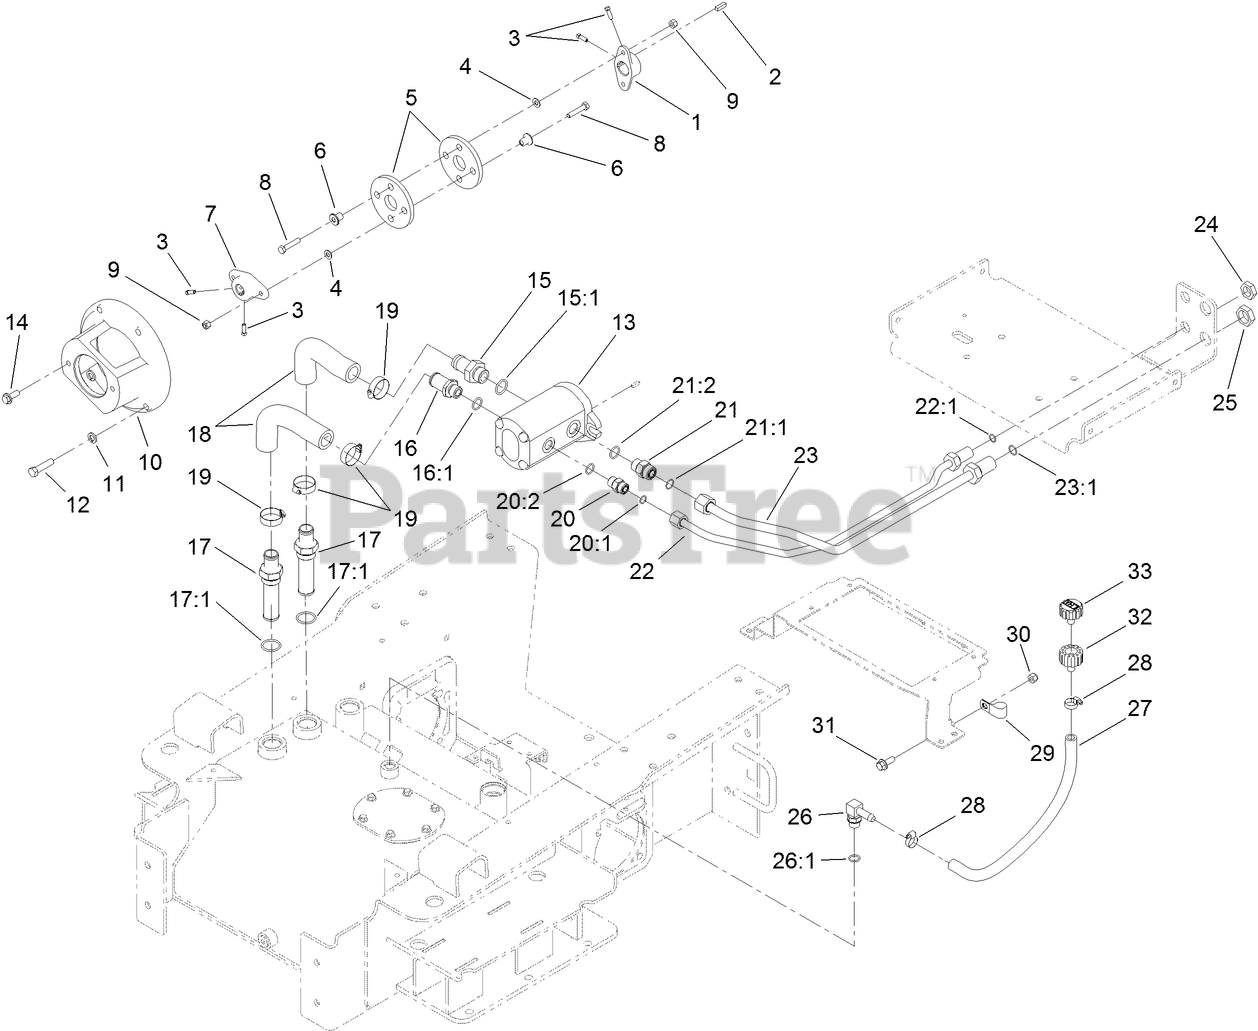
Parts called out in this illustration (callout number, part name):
1	HUB-ENGINE
2	KEY-SQUARE
3	SCREW-SQH
4	WASHER-PLAIN
5	COUPLING-RUBBER
6	SPACER
7	HUB-PUMP
8	SCREW-HH
9	NUT-LOCK, NI
10	MOUNT-PUMP
11	WASHER-LOCK
12	SCREW-HH
13	HYD PUMP ASM
14	SCREW-HHF
15	FITTING
15:1	O-RING
16	FITTING-STR
16:1	O-RING
17	STRAINER FITTING ASM
17:1	O-RING
18	HOSE-SUCTION
19	CLAMP-HOSE
20	FITTING-STRAIGHT
20:1	O-RING
20:2	O-RING
21	FITTING-STRAIGHT
21:1	O-RING
21:2	O-RING
22	HYD TUBE ASM
22:1	O-RING
23	HYD TUBE ASM
23:1	O-RING
24	NUT-BULKHEAD
25	NUT-LOCK, BULKHEAD
26	FITTING-ELB 90
26:1	O-RING
28	CLAMP-HOSE
29	CLAMP-R
30	NUT-LOCK, NI
31	SCREW-HHF
32	ADAPTER-BREATHER
33	BREATHER
